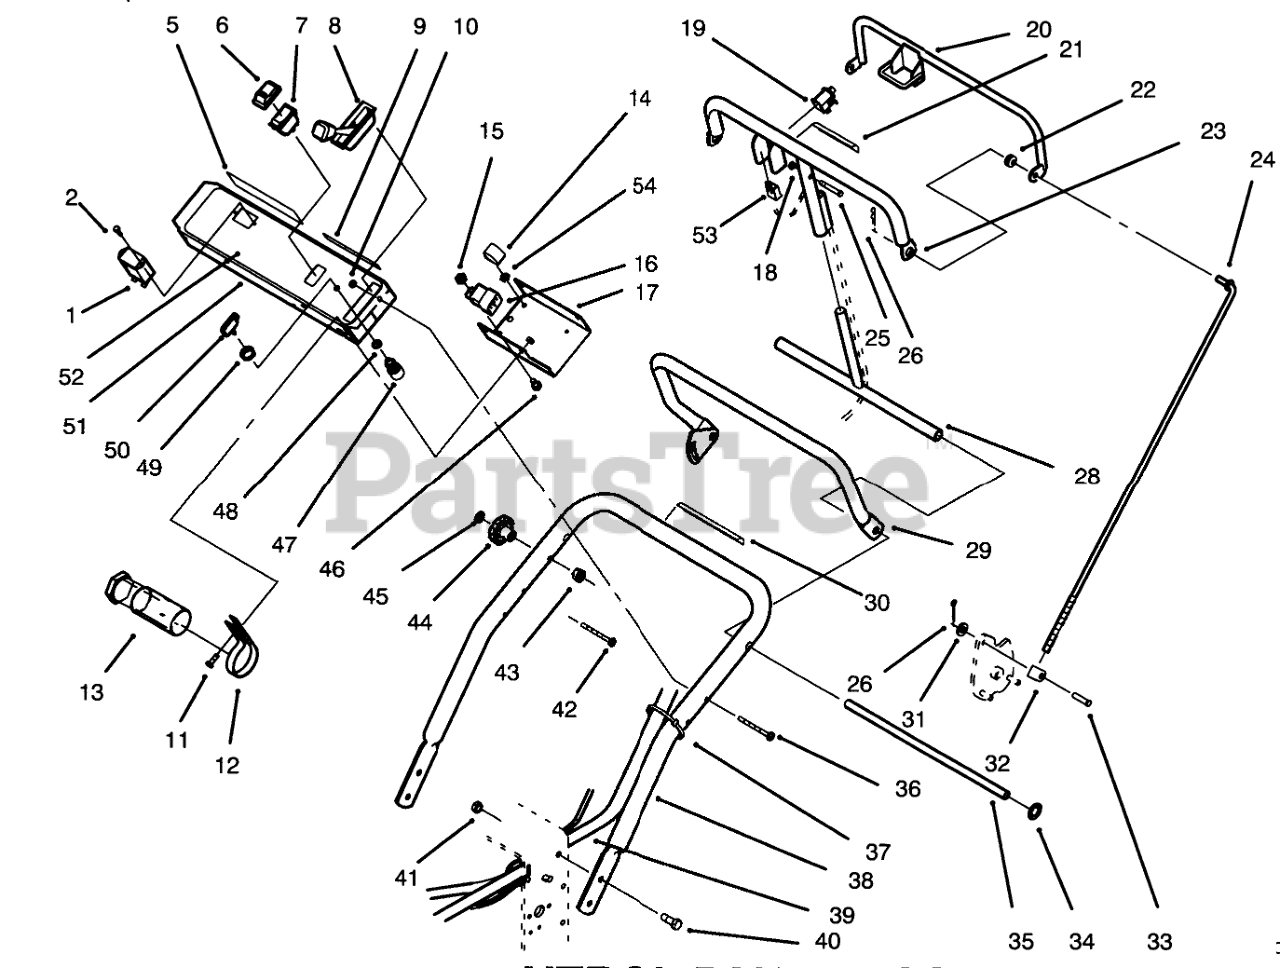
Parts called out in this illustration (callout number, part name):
1	HOURMETER
2	SCREW-HWH
5	DECAL-INSTRUCTION, SAFETY
6	BOOT-SWITCH
7	SWITCH
8	CONTROL-THROTTLE
9	DECAL-INSTRUCTION
10	NUT-LOCK, NI
11	SCREW-SHWH
12	CLAMP-R
13	TUBE-MANUAL
14	Module
15	NUT-LOCK, NI
16	RELAY
17	Panel-Bottom
18	NUT-LOCK, NI
19	SWITCH-BAIL
20	Bail
21	DECAL - CONTROL BAR
22	GROMMET-RUBBER
23	Bar
24	ROD-CONTROL
25	SCREW-SHH
26	PIN-COTTER
28	Pivot Control Assembly
29	REFERENCE HANDLE WA B
30	DECAL-WARNING
31	WASHER-PLAIN
32	FITTING-ROD
33	PIN-CLEVIS
34	NUT-PUSH-ON, CIRCULAR
35	PIVOT ROD
36	SCREW-SHH
37	TIE-CABLE
38	UPPER HANDLE R
39	WIRE HARNESS-14HP HYDRO
40	SCREW-HHF
41	NUT-HF
42	SCREW-CARR
43	SPACER
45	BOLT RETAINER
46	SCREW-HH
47	SWITCH-STARTER
48	SCREW-HHF
49	NUT-HH
50	KEY-IGNITION
51	Panel-Control
52	DECAL - CONTROL PANEL
53	CONNECTOR-BODY
54	WASHER-LOCK/EXT
